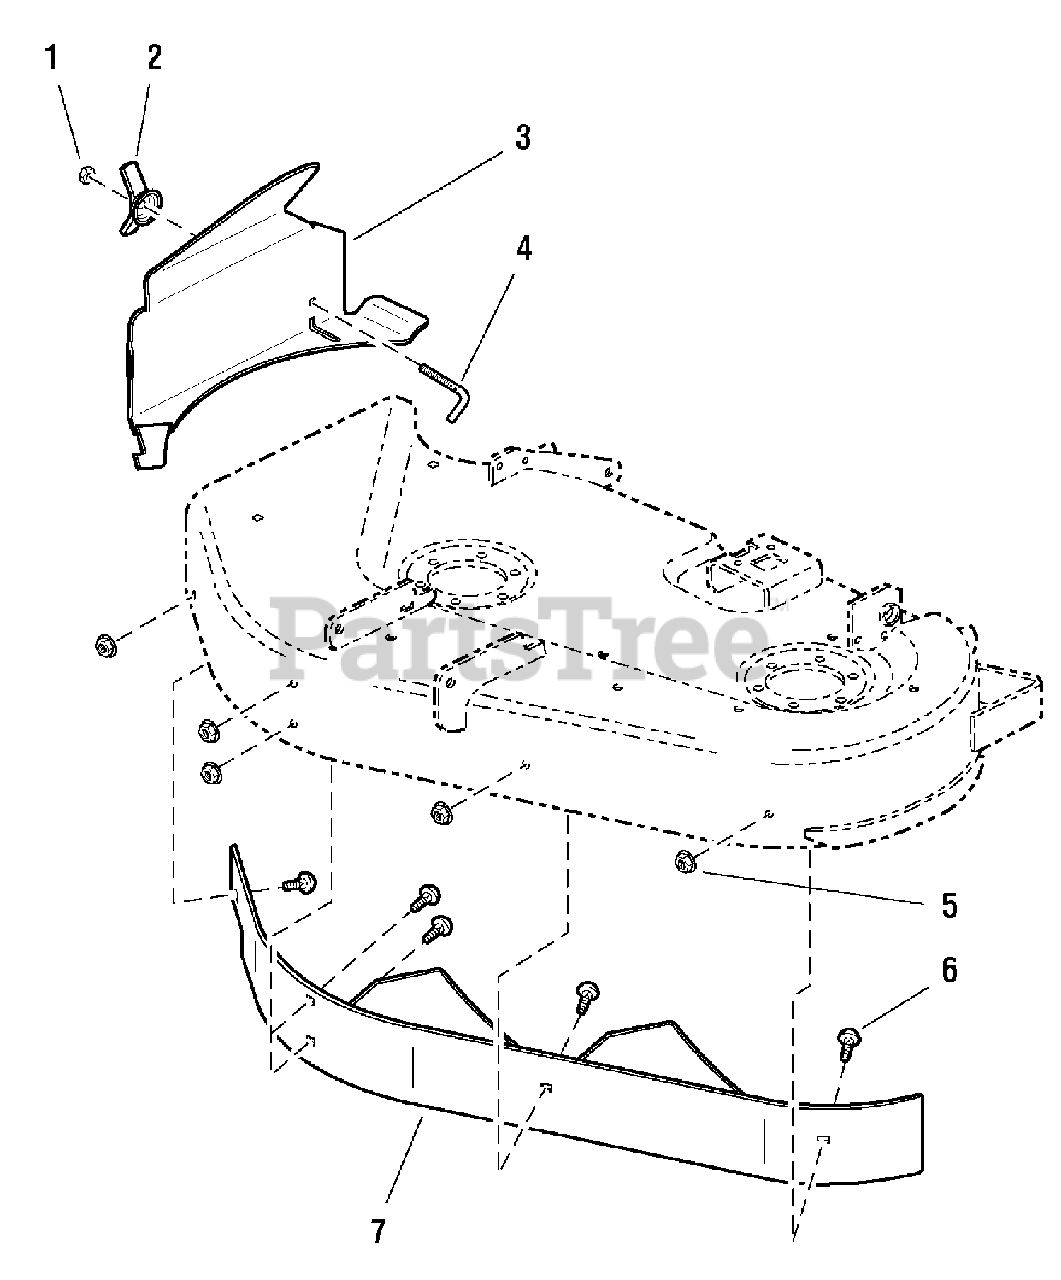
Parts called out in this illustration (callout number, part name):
1	NUT, Hex Lock, 5/16-18
2	WING NUT
3	MULCH PLATE
5	NUT, Hex Serrated Flange, 5/16-18
6	CARRIAGE BOLT, 5/16-18 x 3/4
7	BAFFLE ASSEMBLY, 34"
